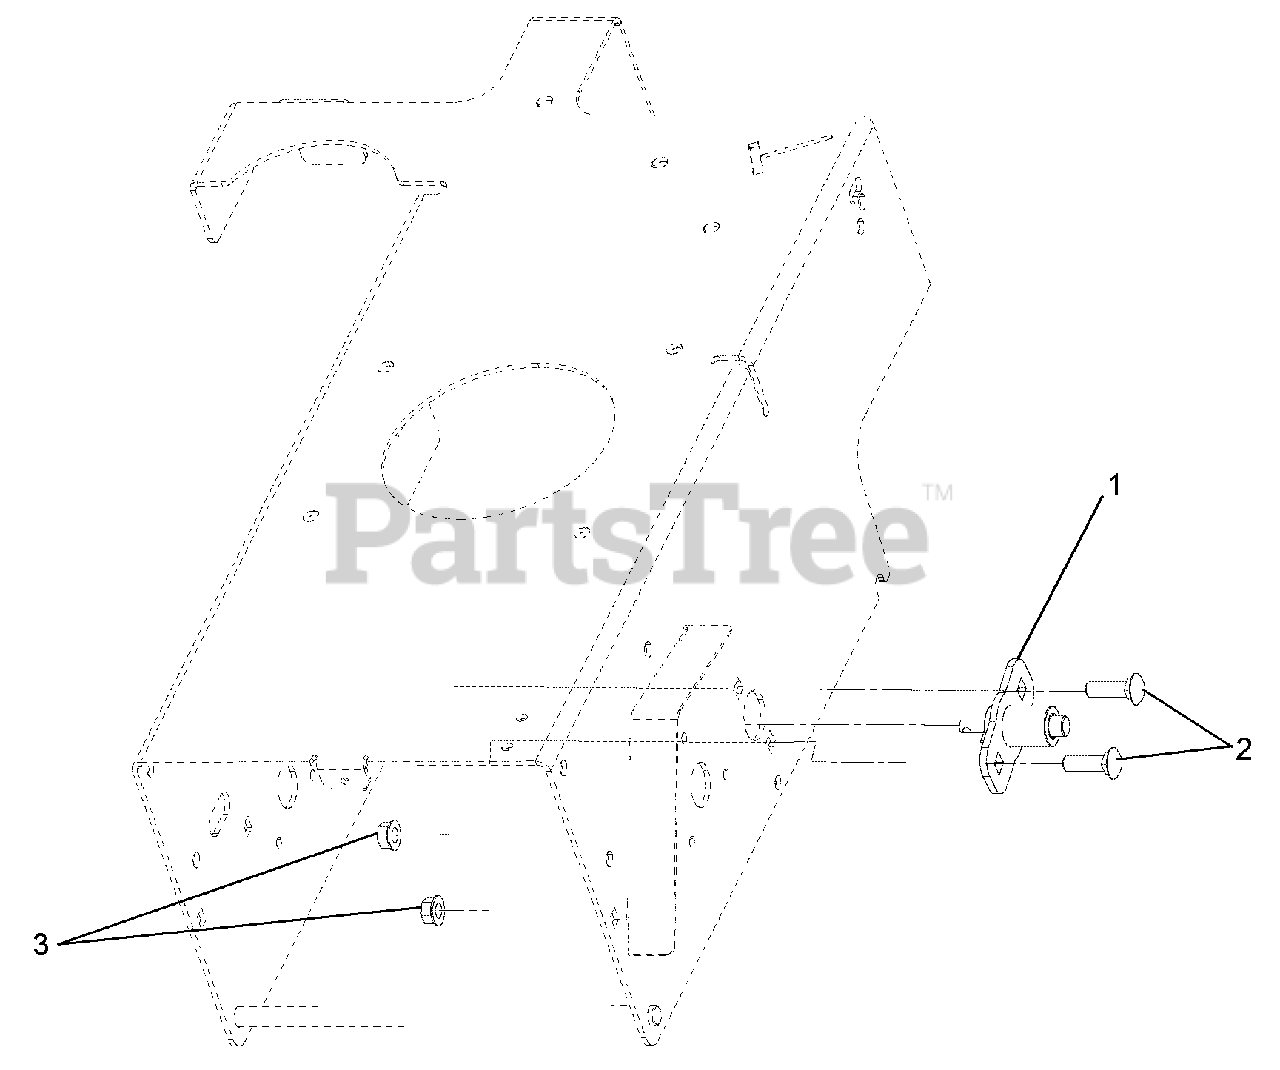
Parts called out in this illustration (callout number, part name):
1	Kit, Pin Brake
2	Bolt, Round Head Square Neck .38-16 x 1.25 Grade 5
3	Nut, Flange .375-16
